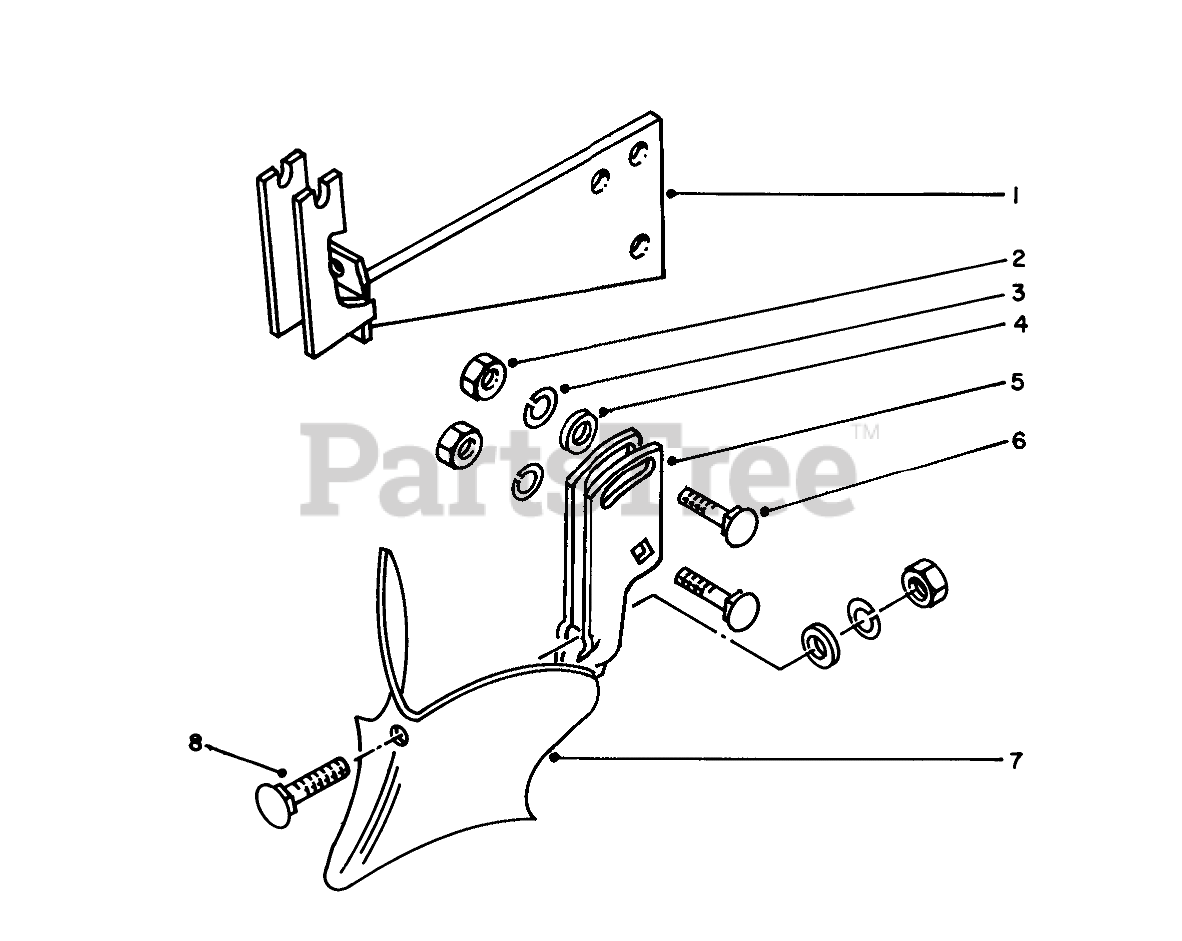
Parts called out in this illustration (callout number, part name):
1	Support
2	NUT-HEX
3	WASHER-LOCK
4	WASHER-FLAT
5	Holder
6	BOLT-CARR
7	Shovel
8	Plow Bolt
